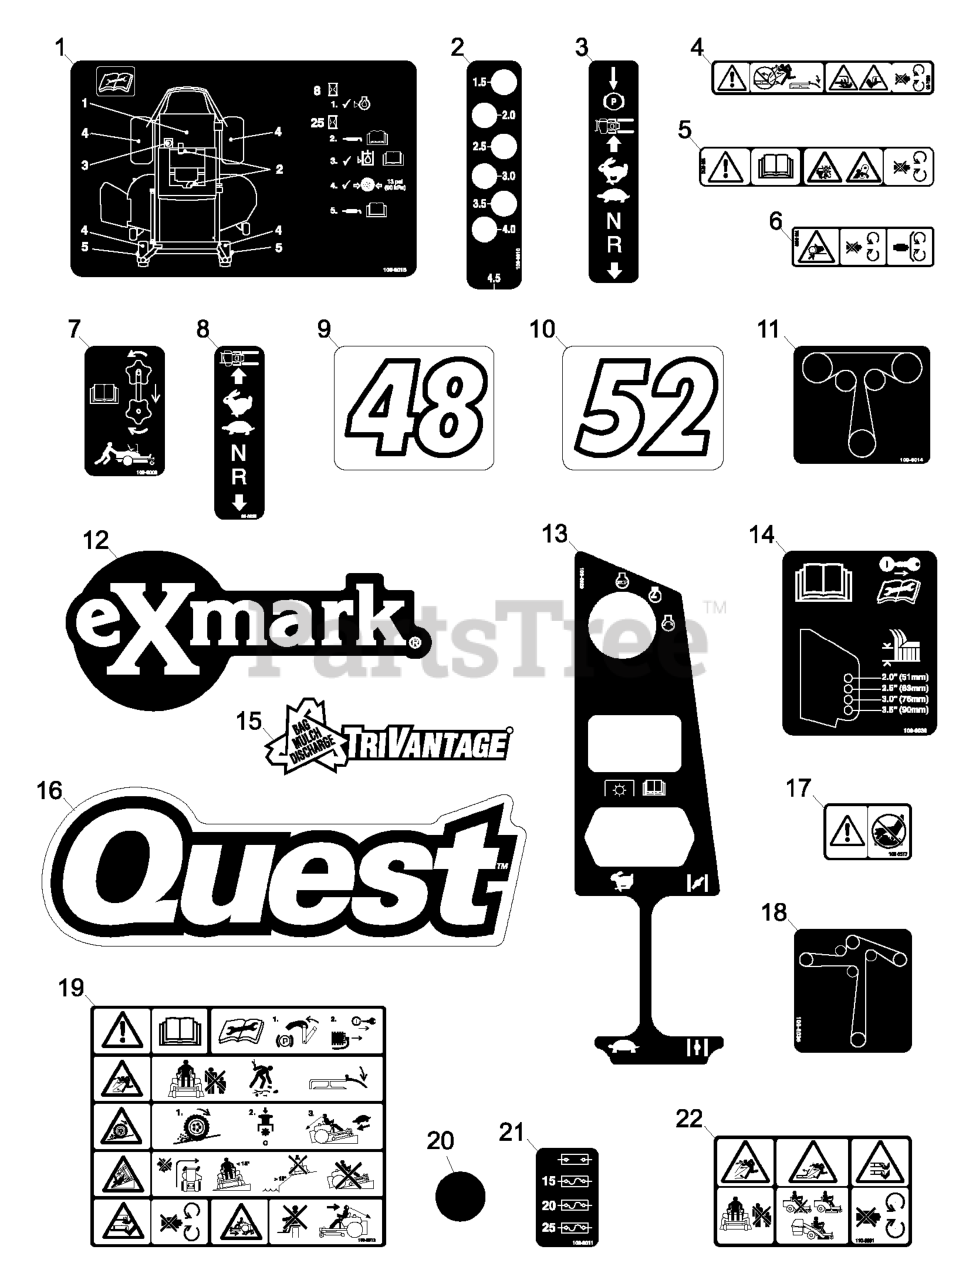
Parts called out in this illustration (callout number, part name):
1	DECAL-SERVICE AID
4	DECAL-DANGER
5	DECAL-DANGER
6	DECAL-WARNING, BELT SHIEL
7	DECAL-DRIVE RELEASE
8	DECAL-CONTROL, MOTION
9	DECAL,DECK 48
10	DECAL,DECK 52
11	DECAL-ROUTING, BELT
12	DECAL,EXMARK LOGO
13	DECAL-CONSOLE
14	DECAL-ROLLER, ANTI-SCALP
16	DECAL,QUEST LOGO
17	DECAL-WARNING
18	DECAL-ROUTING, BELT
21	DECAL-FUSE BLOCK
22	DECAL-DANGER
